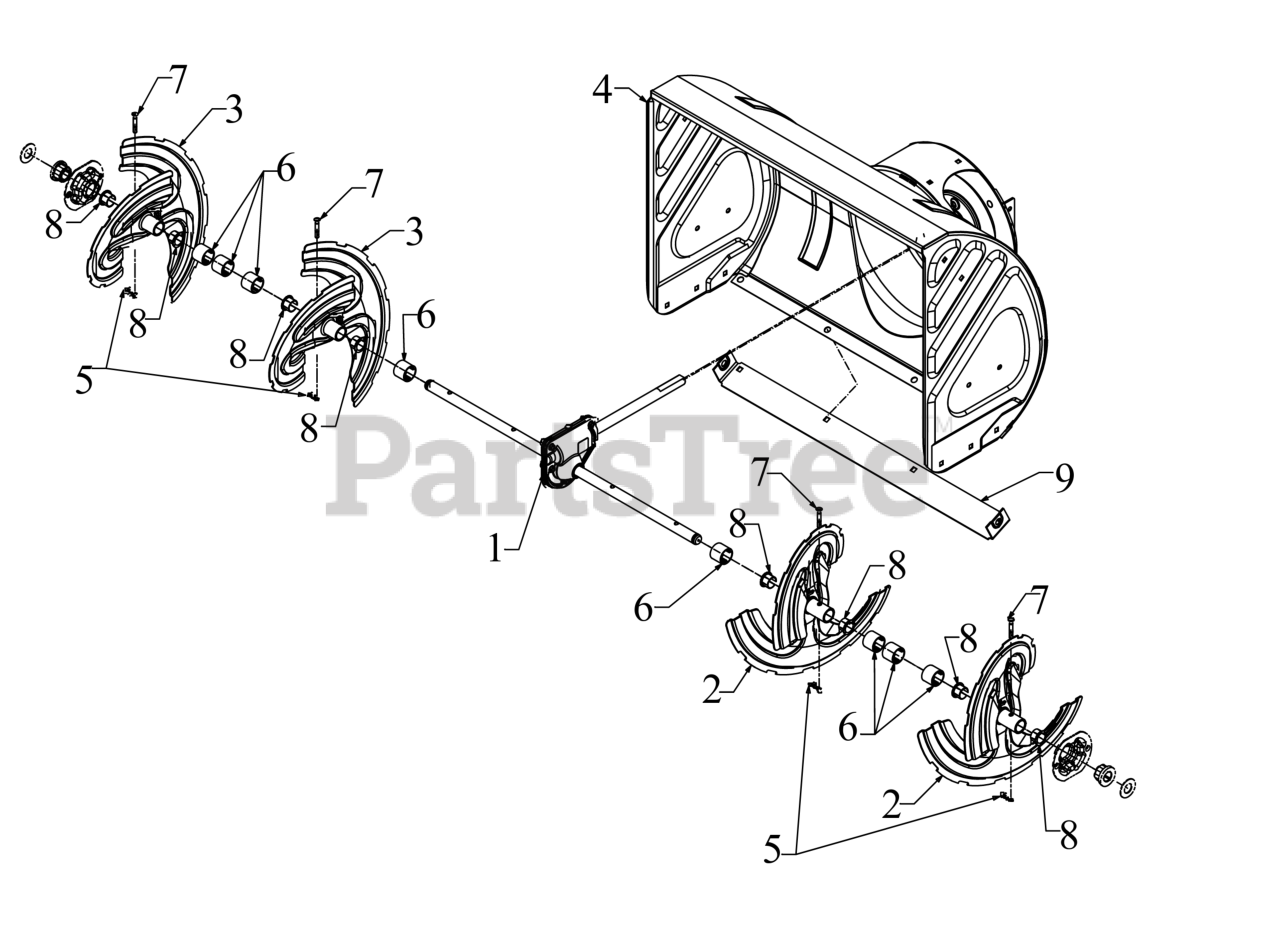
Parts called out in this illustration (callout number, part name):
1	GEARBOX ASSEMBLY 28"
5	BOW TIE COTTER PIN 1/4-5/16
6	SPACER 1.25OD x .75ID X1.00 LG
7	SHEAR PIN .25 x 1.50 GR2
7	Cub Cadet SHEAR PINS (2X SNOW)
7	SHEAR PINS QTY 4
8	FLANGE BUSHING
